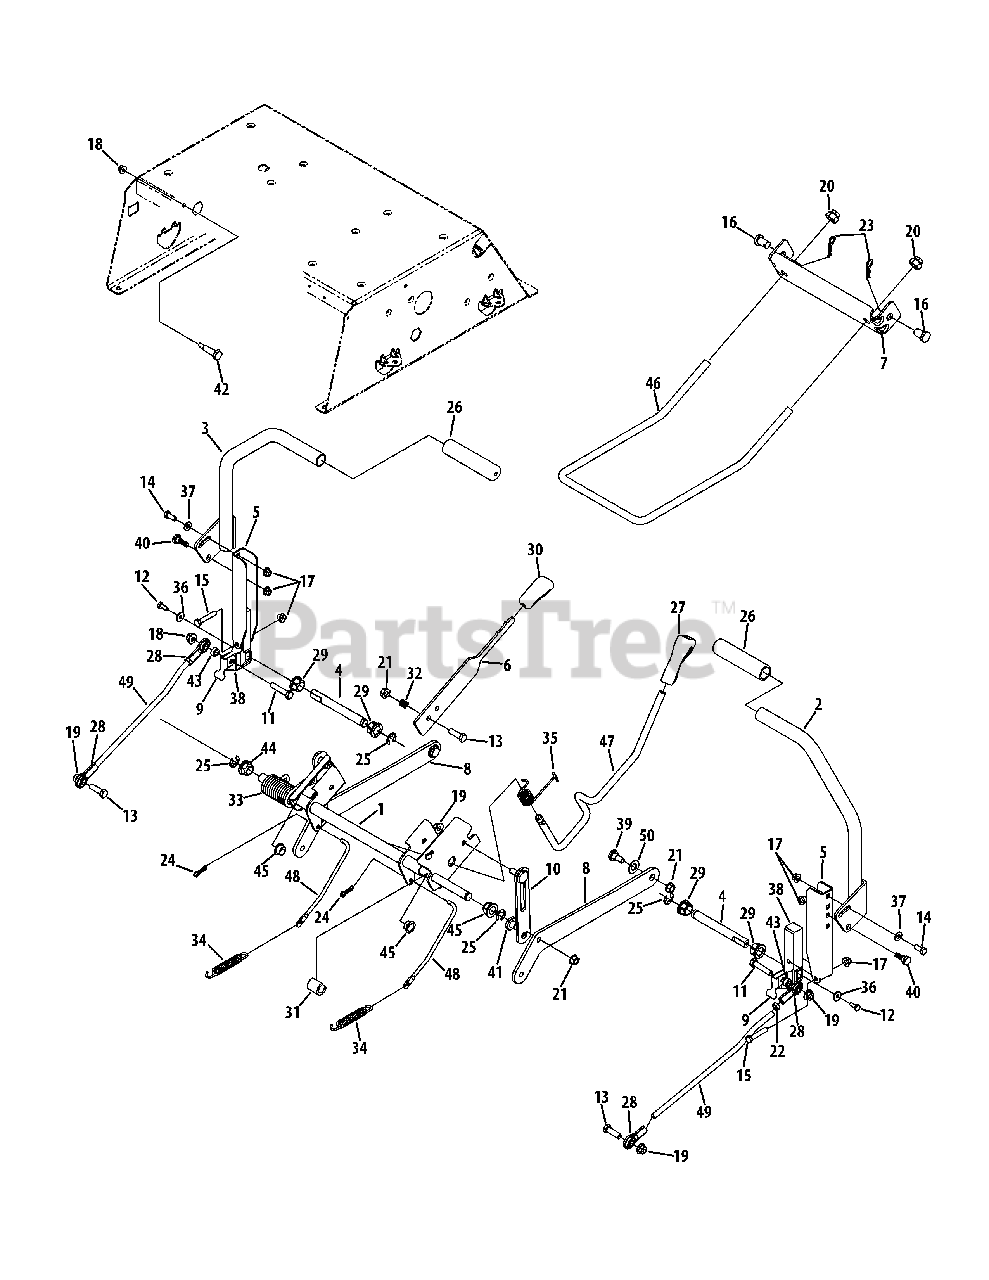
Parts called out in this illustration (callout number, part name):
1	Deck Lift Shaft Assembly
2	RH Lapbar Lever Assembly
3	LH Lapbar Lever Assembly
4	Shaft Control
5	Lapbar Pivot Bracket
6	Brake/Shabs Handle
7	Front Deck Hanger Bracket
8	Deck Lift Arm Plate
9	Actuator Switch Bracket
10	Link Lift Plate
11	Hex Screw, 3/8-16 x 1.75
12	Hex Lock Screw, 1/4-20 x .625
13	Hex Screw, 3/8-16 x 1.25
14	Hex Screw, 5/16-18 x .75
15	Hex Screw, 5/16-18 x 1.75
16	Clevis Pin, .50 x .78
17	Flange Lock Nut, 5/16-18
18	Flange Lock Nut, 1/4-20
19	Flange Lock Nut, 3/8-16
20	Flex Lock Nut, 1/2-13
21	Hex Lock Nut, 3/8-16, Centerlock
22	Jam Nut, 3/8-24
23	Internal Cotter Pin, .080 x 1.5625
24	Bow-Tie Cotter Pin
25	E-Ring, .625
26	Grip, 1.0 x 5.0
27	Handle Grip, 1/2
28	B/Joint Rode End, .375
29	Hex Flange Bearing, .629
30	Selector Handle
31	Spacer, .62 x 1.00
32	Compression Spring, .50 x .50
33	Torsion Spring, 1.19 x 2.78
34	Extension Spring, .59 x 4.00
35	Torsion Spring
36	Bell Washer, .265 x .75 x .062
37	Flat Washer, .344 x .688 x .065
38	PM Control Hub
39	Shoulder Bolt, 3/8-16 x .496 x .336
40	Shoulder Screw, 5/16-18 x .437 x .268
41	Shoulder Screw, .500 x .434
42	Shoulder Screw, .374 x 1.16
43	Spacer, .380 x .625 x .255
44	Hex Flange Bearing
45	Flange Bearing, .626 x .938 x .344
46	Deck Lift Frong Hanger Rod
47	Deck Lift Handle Rod
48	Brake Rod
49	Lapbar Rod Control
50	Flat Washer, .510 x 1.00 x .060
